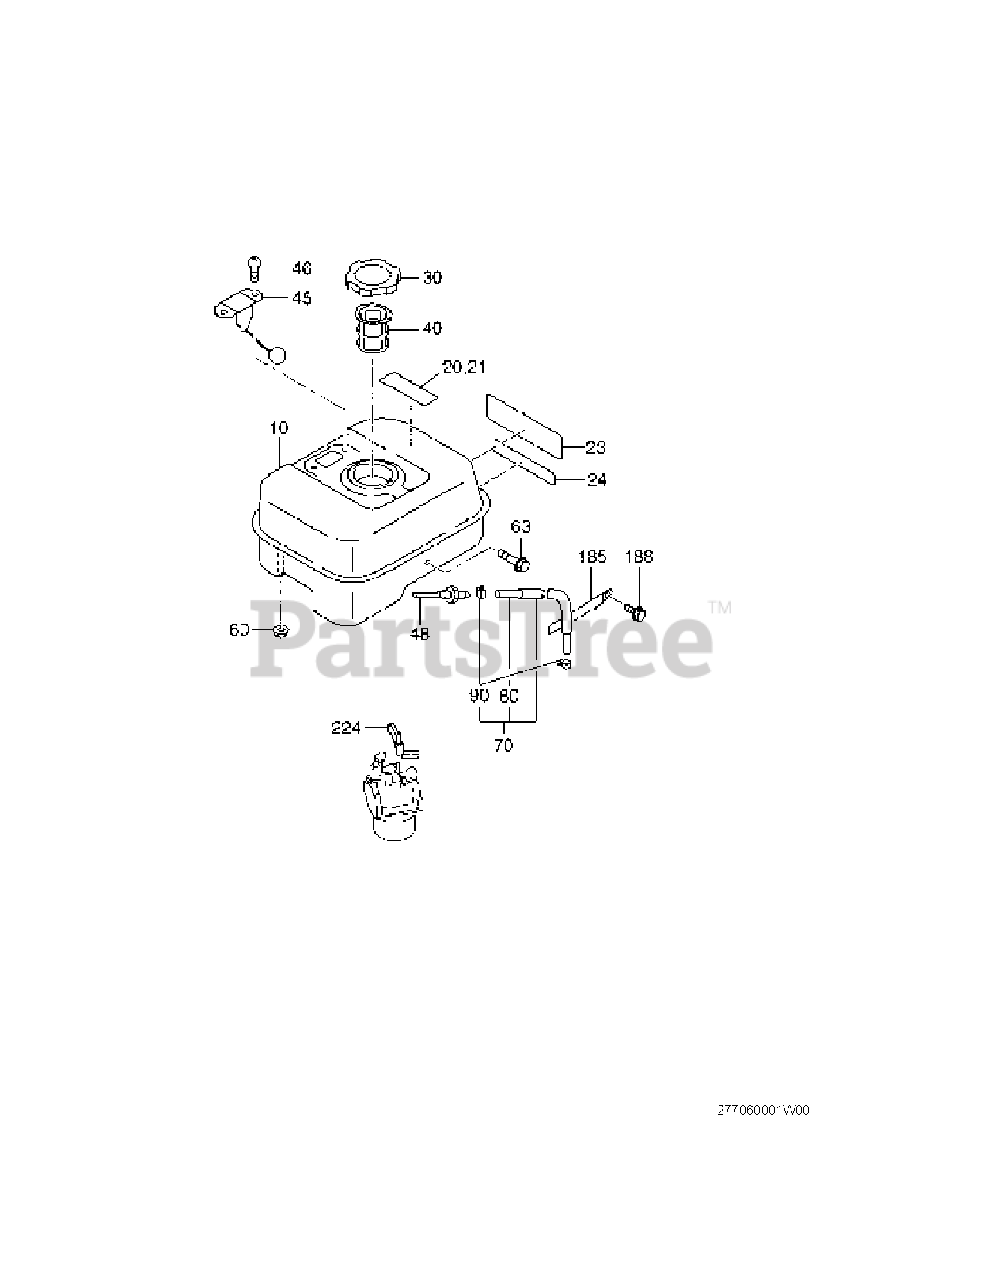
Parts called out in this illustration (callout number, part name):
20	LABEL(WARNING)
23	LABEL(EX16)
30	FUEL TANK CAP CP
224	CHOKE LEVER CP
